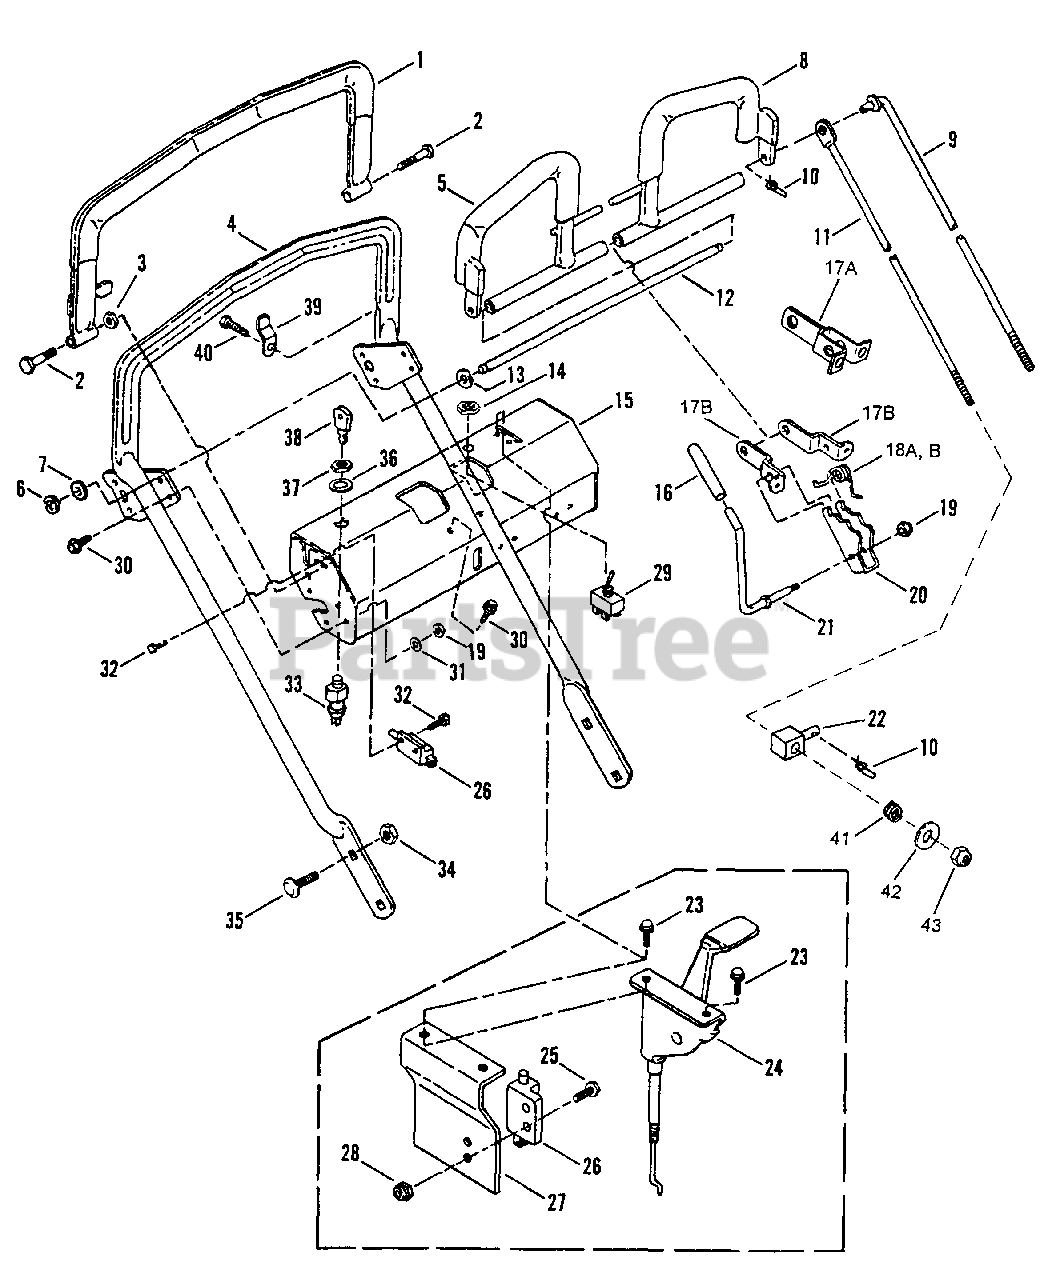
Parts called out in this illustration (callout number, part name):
1	BAIL, OPC
2	BOLT, 1/4-20 X 1-3/4" GD5 YZ
3	NUT, 1/4-20 Hex Jam
4	HANDLE, Loop
5	LEVER, Traction (Right Hand)
6	E-RING, 1/2"
7	BUSHING, 1/2" Machine
8	LEVER, Traction (Left Hand)
9	ROD, Traction
10	COTTER-PIN, 1/2" Self-Locking
11	ROD, Brake
12	ROD, Pivot
13	WASHER, 1/2 Flat
14	NUT, 1/2-27 (Special)
15	CONTROL, Console
16	GRIP, Neutral Latch
17A	MOUNT, Neutral Latch
17B	BRACKET, Neutral Mounting
18A	SPRING, Torsion R.H.
18B	SPRING, Neutral
19	NUT, 1/4-20 Hex Nyloc
20	LATCH
21	LEVER, Neutral Latch
22	SWIVEL
23	SCREW, #10-24 x 1/2" Hex Washer Self-Tap (Torx)
24	CONTROL, Throttle
25	SCREW, #10-24 x 1/2" Hex Head, Machine
26	SWITCH, OPC
27	BRACKET, Reverse Throttle
28	NUT, #10-24 Hex Nyloc
29	SWITCH
30	SCREW, 1/4-20 x 1/2" Self-Tapping
31	WASHER, 1/4 Flat
32	SCREW, #12-14 x 1/2" Hex Slotted Head, Self-Tapping
33	SWITCH, ON-OFF
34	NUT, 3/8-16 HEX NYLON LOCK
35	BOLT, 3/8-16 x 1" Carriage, Grade 2
36	WASHER, 5/8 Internal Tooth Lock
37	NUT, 5/8-32 Hex (Special)
38	KEY, Switch (With Cover)
39	SPRING, Loop Handle
40	SCREW, 1/4-20 x 3/8" Hex Washer Head, Self-Tapping
41	SPRING, Friction Pack
42	WASHER, 3/8" USS
43	NUT, 3/8-16 HEX NYLON LOCK
